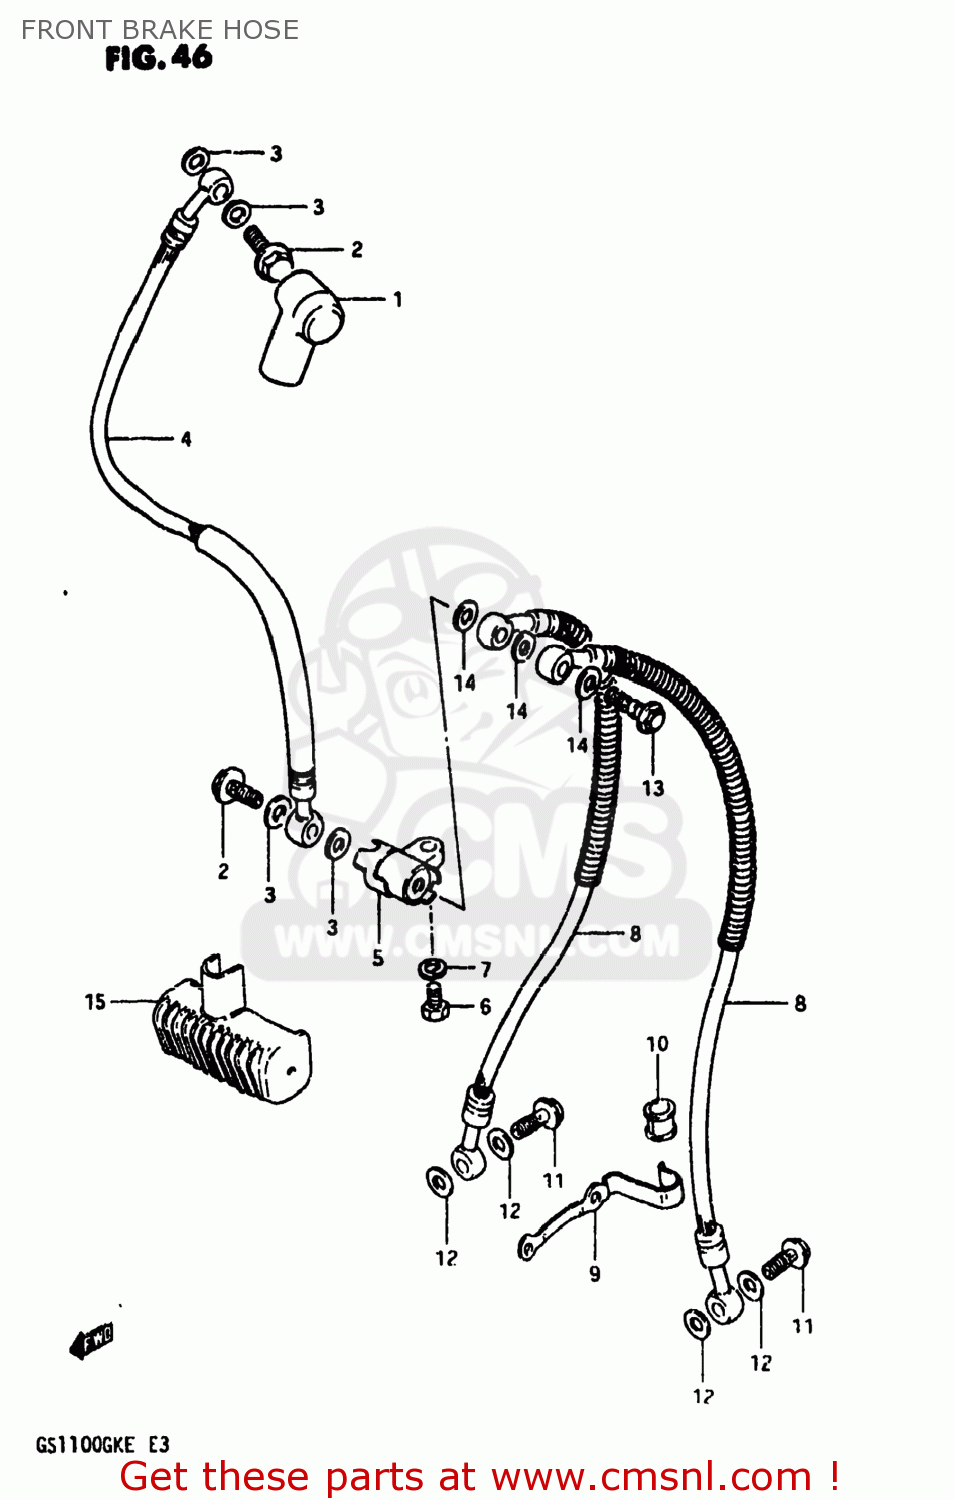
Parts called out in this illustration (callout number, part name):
1	BOOT,MASTER CYLINDER
2	BOLT UNION
3	WASHER
4	HOSE,FRONT BRAKE
5	JOINT,BRAKE HOSE
6	BOLT
7	LOCK WASHER
8	HOSE,BRAKE
9	GUIDE,BRAKE HOSE NO.2
10	BUSH,BRAKE HOSE GUIDE,NO.2
11	BOLT UNION
12	WASHER
13	BOLT,UNION
14	WASHER
15	COVER,BRAKE HOSE JOINT
